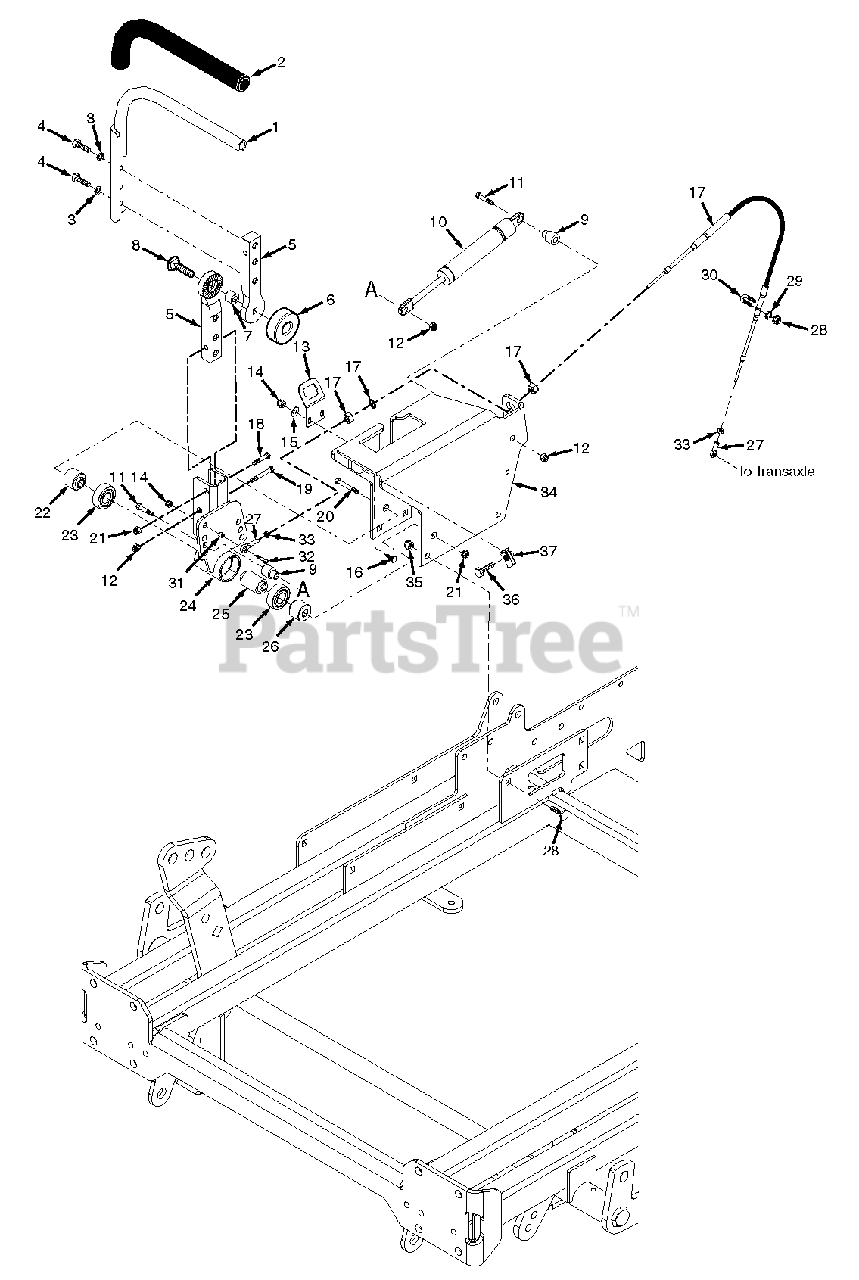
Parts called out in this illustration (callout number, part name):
1	Handle Bar w/Grip, LH
1	Handle Bar w/Grip, RH
2	Grip, Control Handle
3	Lockwasher, 5/16-" Spring
4	Bolt, Hex Head 5/16-18 x 1'
5	Pivot, Control Lever
6	Knob, Control Handle
7	Spacer, Rubber
8	Bolt, Carriage 3/8-16 x 1-1/2"
9	Spacer
10	Damper
11	Bolt, Hex Head 5/16-18 x 2"
12	Nut, Elastic Stop 5/16-18
13	Bracket, Operator Presence Switch
14	Nut, Elastic Stop 1/4-20
15	Flatwasher, 1/4-.312 x .750 x .065
16	Bolt, Carriage 1/4-20 x 3/4"
17	Control Cable, Hydro
18	Bolt, Hex Head 5/16-18 x 2"
19	Bolt, Hex Head 5/16-18 x 2"
20	Bolt, Hex Head 3/8-16 x 6"
21	Nut, Elastic Stop 3/8-16
22	Spacer, Controls
23	Bearing
24	Pivot Weldment, Control Arm LH
24	Pivot Weldment, Control Arm RH
25	Spacer, Bearing
26	Spacer, Controls
27	Rod End, 1/4-28 RH Thread
28	Nut, Jam 5/16-24 UNF-2B
29	Lockwasher, 5/16" Spring
30	U-Bolt, 5/16-24
31	Spacer
32	Bolt, Hex Head 1/4-20 x 1-1/4"
33	Nut, Jam 1/4-28 UNF
34	Bracket Weldment, Control Lever RH w/Decal
34	Bracket Weldment, Control Lever LH w/Decal
35	Nut, Serrated Flange 5/16-18
36	Bolt, Hex Head 3/8-16 x 2" Special
37	U-Nut, 3/8-16
